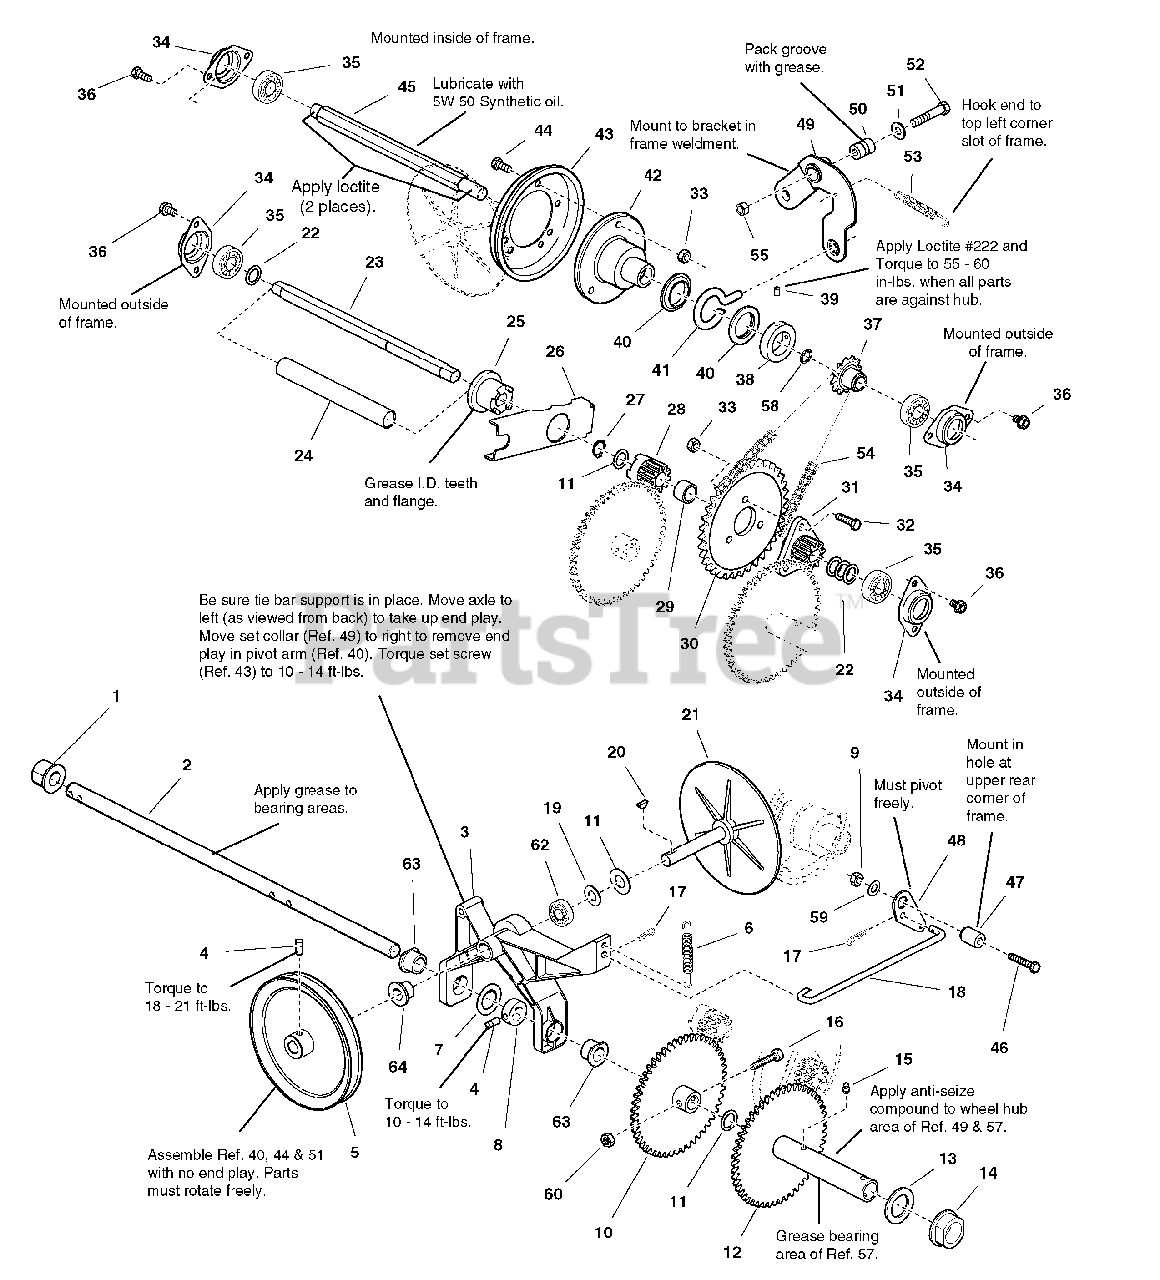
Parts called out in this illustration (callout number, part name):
1	BUSHING, 377/100 ID x 1-13/100 OD x 1 LG, Powdered Metal
2	AXLE, Round
3	ARM, Pivot with Bushings & Bearings
4	SCREW, Set Square Head Cup Point, 5/16-18 x 1/2 G8
5	PULLEY AND HUB ASSEMBLY
6	SPRING, Extension
7	WASHER
8	COLLAR, Set
9	NUT, Hex Flange, 5/16-18 ESNA
10	GEAR AND HUB ASSEMBLY, RH
11	WASHER, 3/4
12	GEAR AND HUB ASSEMBLY, with Bushings
13	WASHER, 1-47/250
14	BUSHING, 1-27/200 ID x 1-157/250 OD x 3/4 LG
15	FITTING, Lube 1/4-28, Tappered with Check Ball
16	CAPSCREW, Hex Head, 5/16-18 x 1-1/2 G8
17	PIN, Quick
18	ROD, Pivot, 9-15/100 LG
19	WASHER, 5/8
20	KEY, Woodruff, 47/250 x 5/8
21	DRIVE DISC w/SPINDLE
22	WASHER, 5/8
23	JACKSHAFT, Double D
24	SPRING, Complete
25	CLUTCH, Sliding, 1/5LG, Powdered Metal
26	ARM, Clutch
27	RING, Retaining Extension
28	GEAR, Stationary Clutch
29	SPACER, Heat Treated, 31/100 LG
30	SPROCKET
31	GEAR, Double D
32	CAPSCREW, Hex Head, 5/16-18 x 1 G5
33	NUT, Hex Keps Conical Washer, 5/16-18
34	RETAINER, Bearing
35	BEARING, Ball
36	SCREW, Hex Washer Head Taptite, 5/16-18 x 5/8
37	SPROCKET, 10 Tooth
38	COLLAR, Set
39	SCREW, Set Square Head Cup Point, 1/4-20 x 1/2
40	COLLAR, Thrust
41	PIN, Loop
42	HUB, Friction Disc
43	DISC, Friction with Insert
44	CAPSCREW, Hex Head, 5/16-18 x 3/4 G5
45	SHAFT, Hex
46	CAPSCREW, Socket-Head, 5/16-18 x 2
47	BUSHING, 11/32 ID x 3/4 OD x 1-3/50 LG
48	BELLCRANK
49	ARM ASSEMBLY, Shift w/Bushing
50	BUSHING, 19/50 ID x 3/4 OD x 1-3/100 LG
51	WASHER, 3/8
52	CAPSCREW, Hex Head, 3/8-16 x 2 G5
53	SPRING, Extension
54	CHAIN, Roller
55	NUT, Hex Flange, 3/8-16 ESNA
58	RING, Retaining External #87
59	WASHER, 11/32 x 3/4
60	NUT, 1/4-20
62	BEARING, Ball
63	BUSHING, 3/4 ID x 1 OD x 3/4 LG, Powdered Metal
64	BUSHING, 5/8 ID x 13/16 OD x 3/4 LG, Powdered Metal
